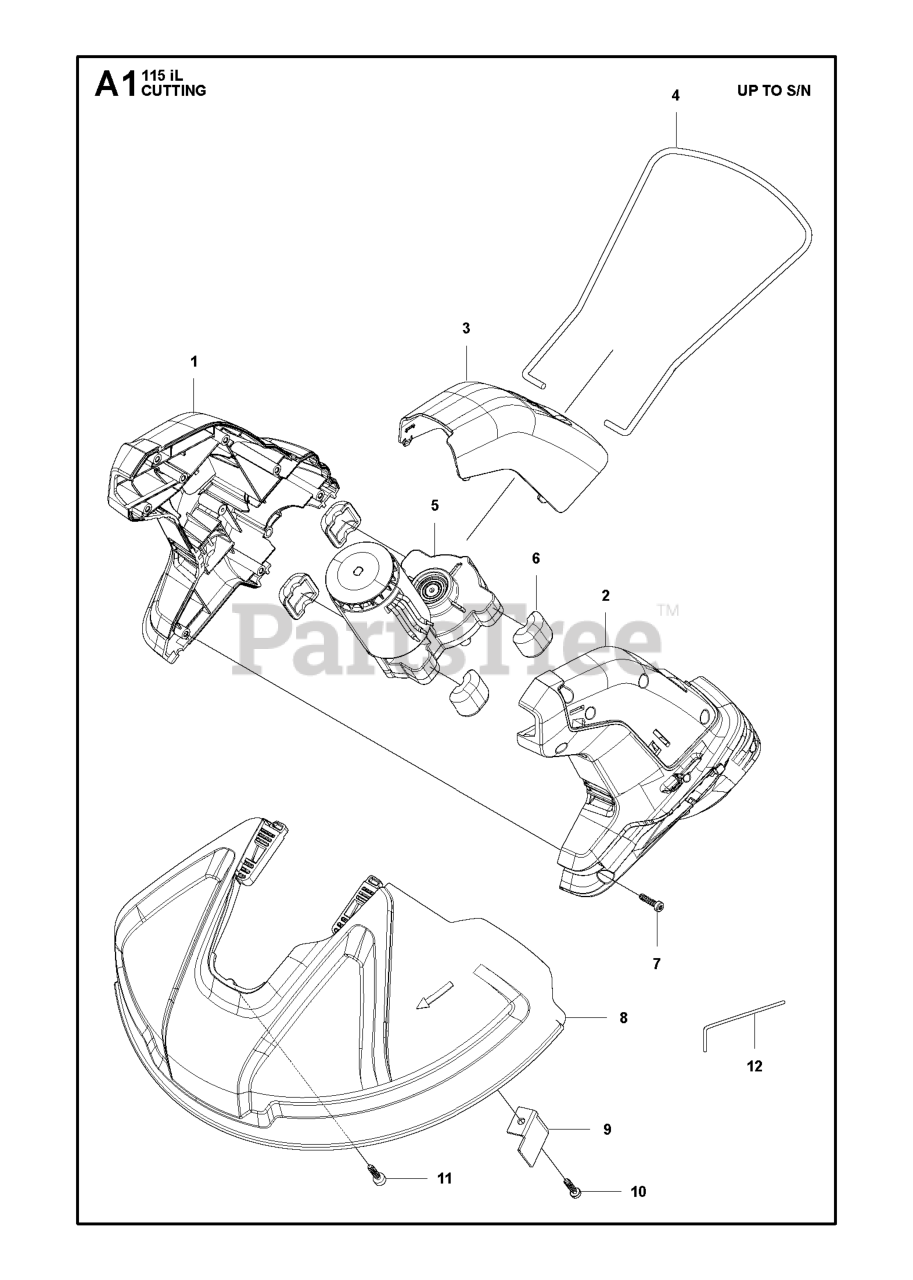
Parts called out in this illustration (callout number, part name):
1	HOUSING MOTOR HOUSING L 36V
2	HOUSING MOTOR HOUSING R 36V
3	COVER MOTOR HOUSING
4	RING PLANT GUARD
5	GEARBOX ASSY 36V
7	SCREW ST4X16
8	GUARD FOR CUTTING HEAD
9	BLADE 330MM
10	SCREW ST4X16
11	SCREW ST4*16
